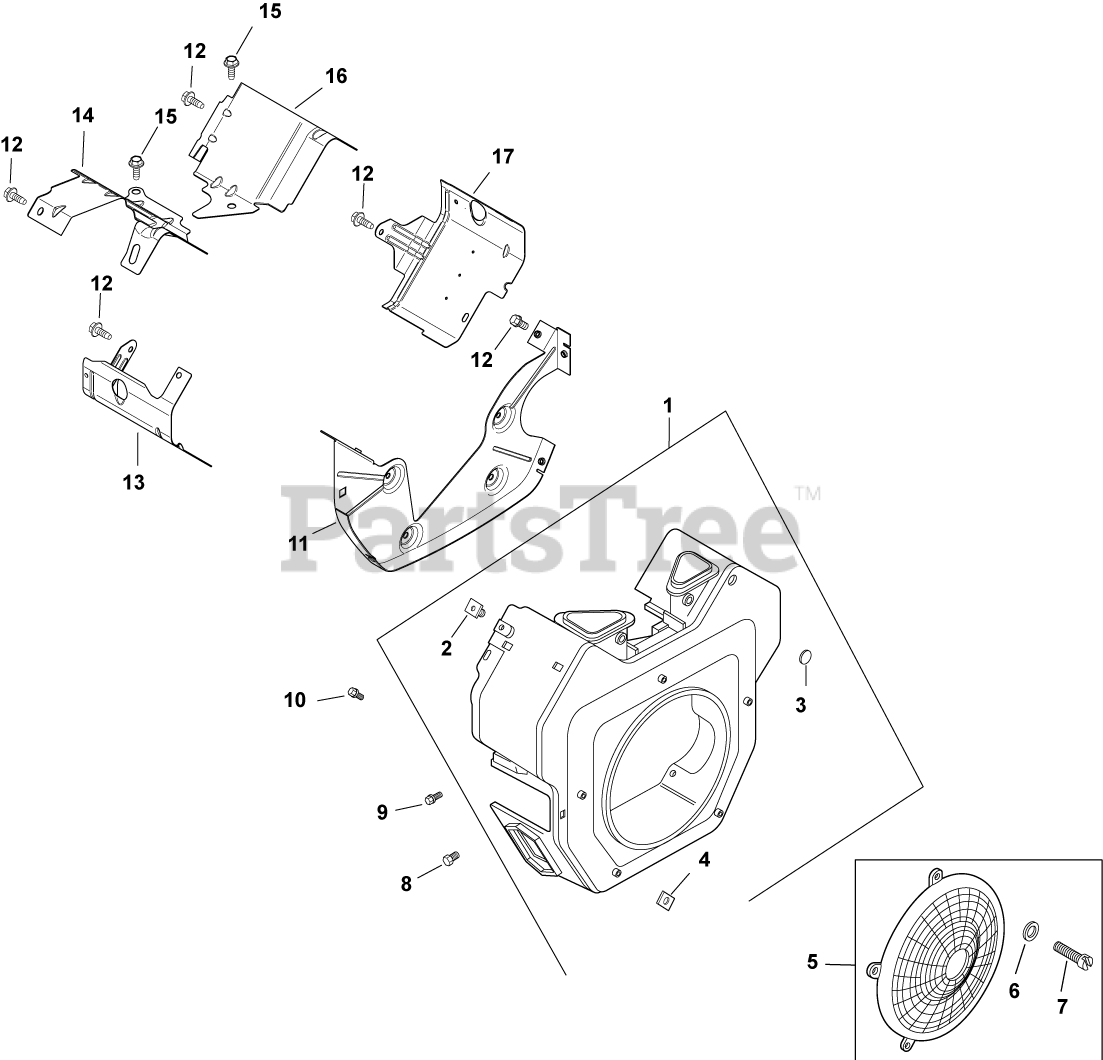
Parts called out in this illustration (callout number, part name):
1	KIT, BLOWER HOUSING ASSEMBLY USE 24 027 479-S
2	NUT, PLASTIC
3	PLUG, BUTTON 9/16
4	NUT, PLASTIC (KM)-USE 25 100 37-S
5	KIT, FIXED GUARD
6	WASHER, FLAT 7/32"
7	SCREW, LBD SCKT PAN M5X0.8X10
8	SCREW,FLG THD FRM M6X1.0X16-(#25086397S)
9	SCREW - USE M-545016-S
10	SCREW,FLG THD FRM M5X0.8X16-(#25086398S)
11	PLATE, BACKING (OIL COOLER)-USE 24 146 5
12	SCREW, FLG THD FRM M5X.8X20-(#25086399S)
13	BAFFLE, VALLEY #2 SIDE-USE 24 063 94-S
14	BAFFLE, VALLEY (CH)-USE 24 063 93-S
15	SCREW, FLG THD FRM M5X.8X10
16	BAFFLE, RIGHT BARREL-USE 24 063 85-S
17	BAFFLE, LEFT BARREL -USE 24 063 88-S
